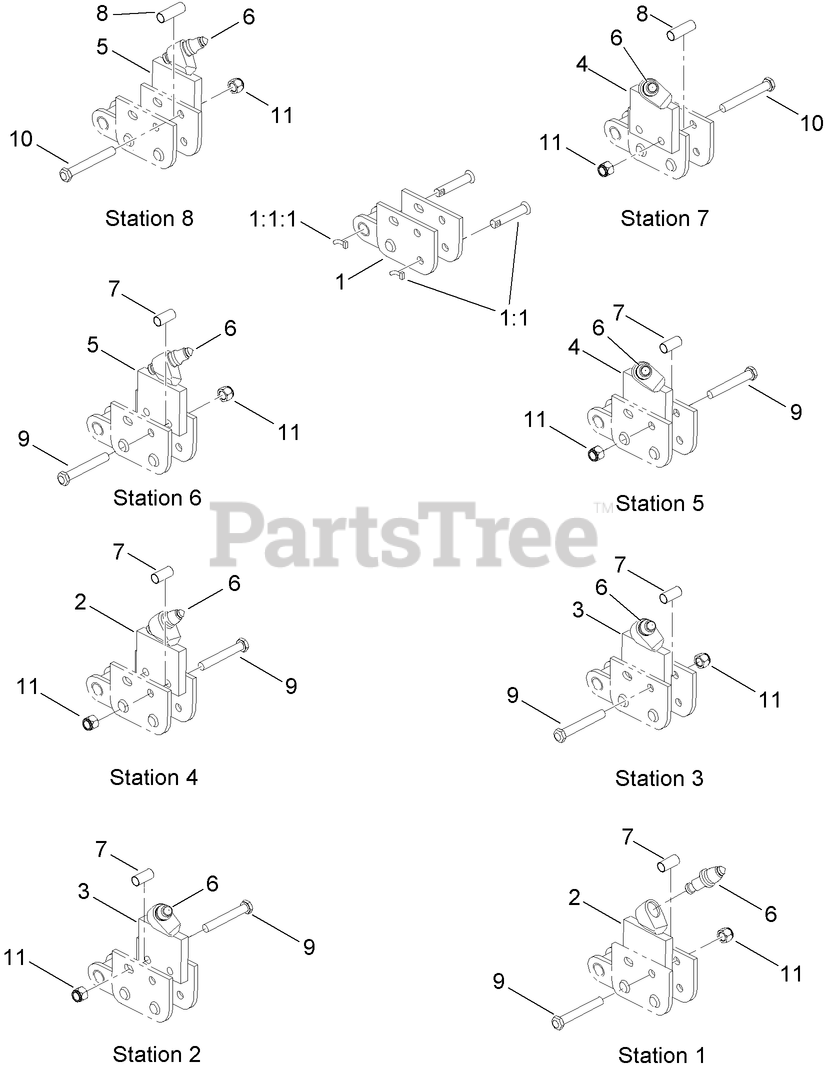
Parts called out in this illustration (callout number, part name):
1	CHAIN REPAIR LINK ASM
1:1	NOTCHED PIN AND KEEPER ASM
1:1:1	PIN-KEEPER
2	HOLDER-BIT, RH CENTER
3	HOLDER-BIT, LH CENTER
4	HOLDER-BIT, RH
5	HOLDER-BIT, LH
6	BIT-CARBIDE, FULL CAB
7	SPACER-TUBE, INSIDE ADAPTER
8	SPACER-TUBE, OUTSIDE MOUNT
9	BOLT-HH
10	BOLT-HH
11	NUT-LOCK
